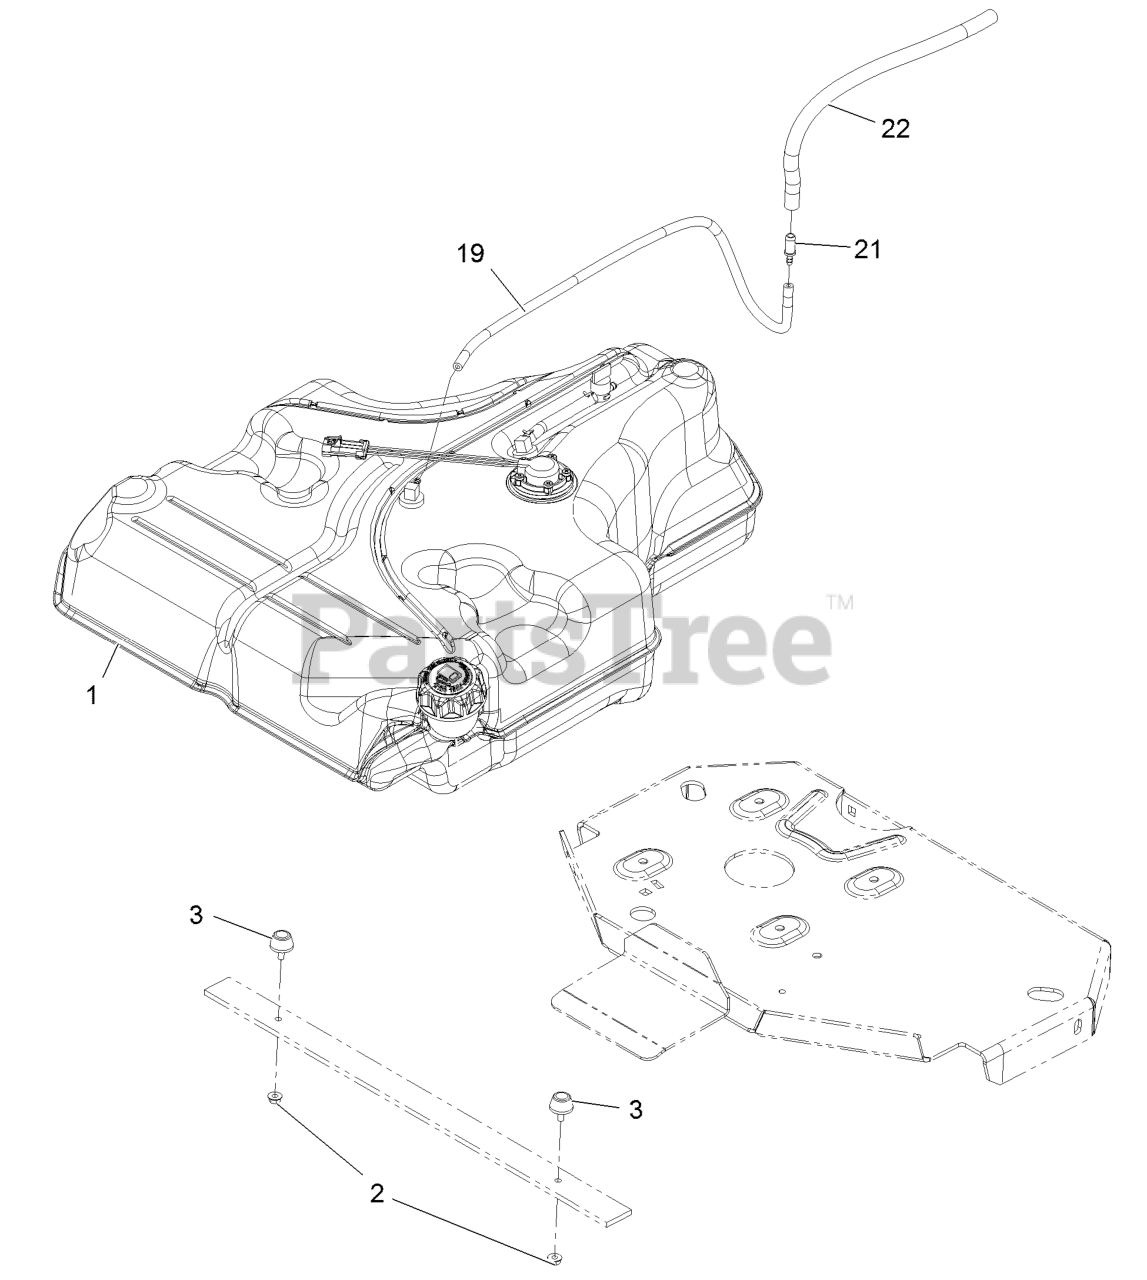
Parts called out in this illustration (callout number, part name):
2	NUT-JAM
19	HOSE-FUEL
21	FITTING-STRAIGHT
22	HOSE-FUEL
